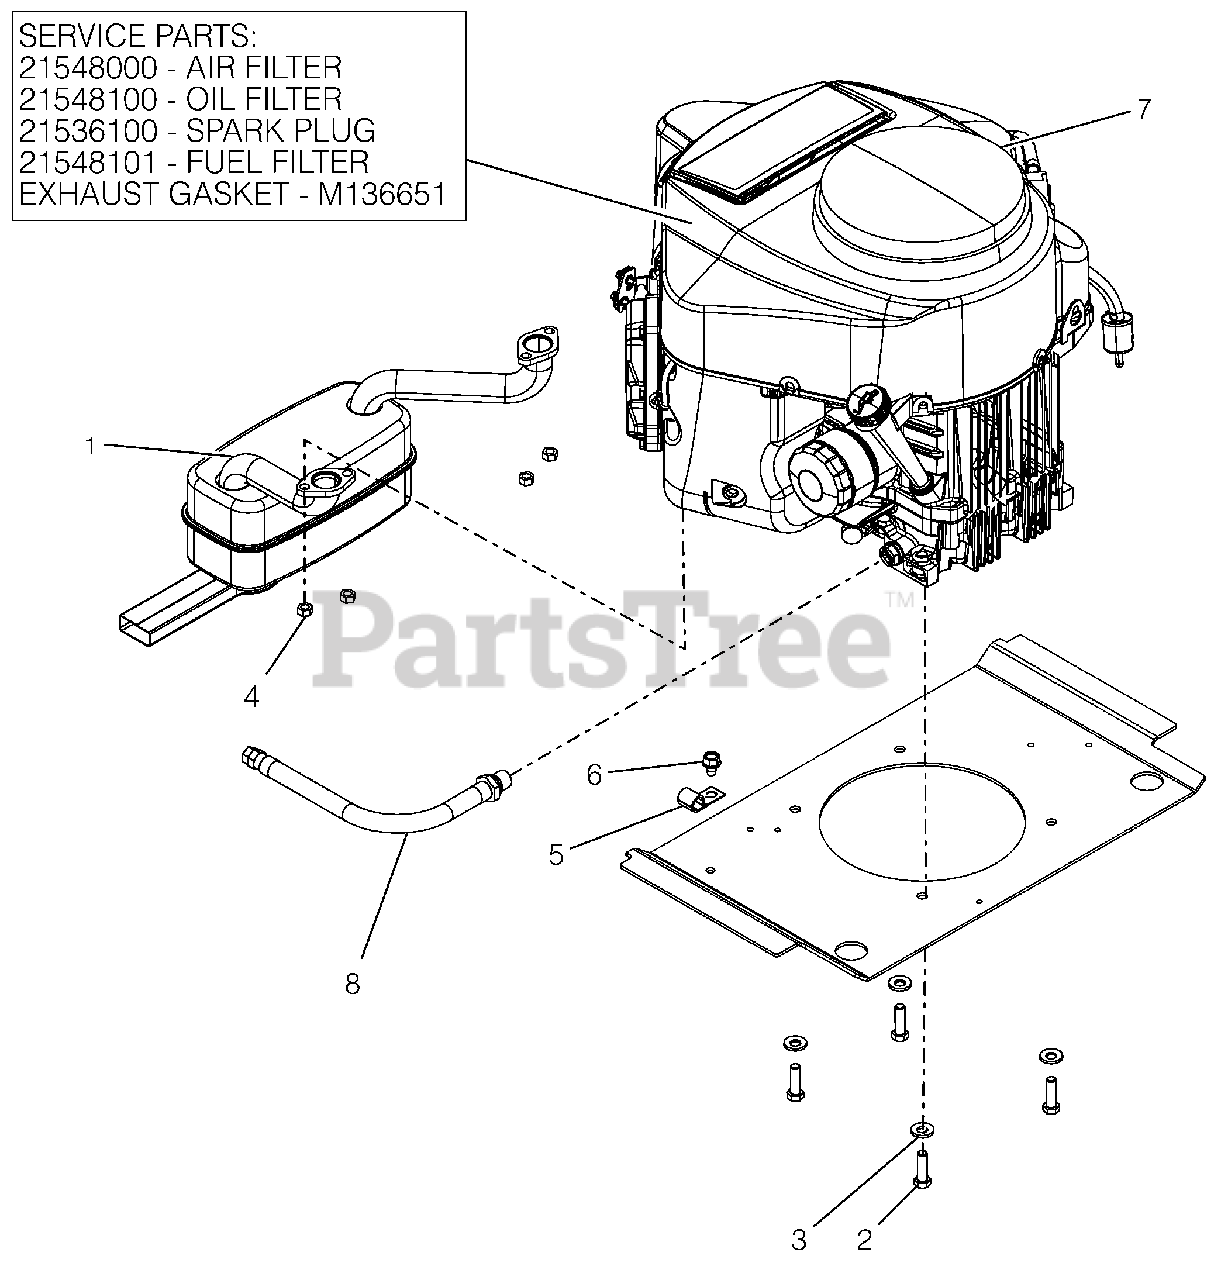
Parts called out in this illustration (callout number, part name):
1	MUFFLER, KAWASAKI
2	BLT-HEX.38-16X1.25 G5YZ NYTORQ
3	WASHER, 3/8" SPRING DISC
4	NUT-LK-TOP M8-1.25 YWZC
6	@SCR-TAP .38-16X.50 HWH TR YWZ
7	ENGINE, KAWASAKI FR691 23HP
7	AIR FILTER, KAWASAKI FR
7	OIL FILTER, KAWASAKI FR
7	PLUG, SPARK
7	FUEL FILTER-KAWASAKI FR
7	GASKET, MUFFLER #
8	HOSE, OIL DRAIN
